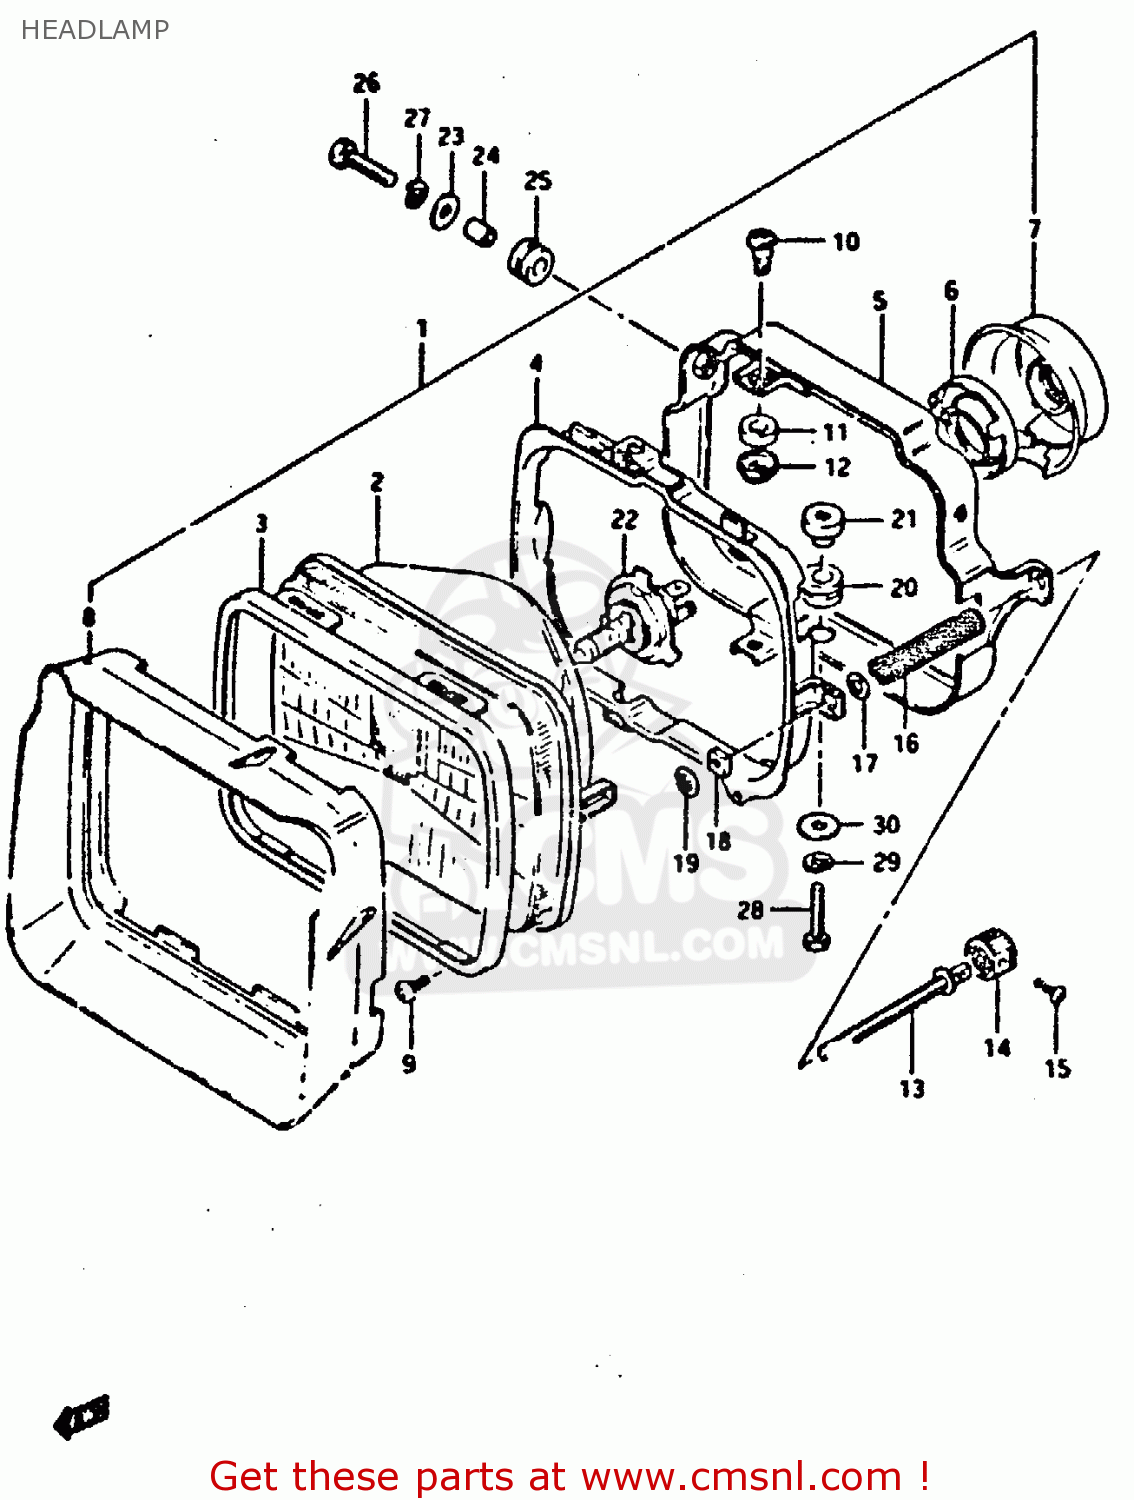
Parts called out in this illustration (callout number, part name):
1	HEADLAMP ASSEMBLY
2	LAMP UNIT
3	RETAINER
4	RING,MOUNTING
5	HOUSING
6	HOLDER
7	COVER,HEADLAMP SOCKET
8	SHADE,HEADLAMP UNIT
9	SCREW
10	SCREW
11	SPACER
12	NUT,ADJUSTING
13	SCREW,ADJUSTING
14	KNOB,ADJUSTER
15	SCREW
16	SPRING
17	WASHER
18	NUT
19	NUT,HEADLAMP ADJUSTER
20	CUSHION
21	NUT
22	BULB(12V60/55W,H4)
23	WASHER
24	SPACER (6.1X8X9.5)
25	CUSHION
26	BOLT
27	LOCK WASHER
28	SCREW(6X20)
29	LOCK WASHER
30	WASHER
